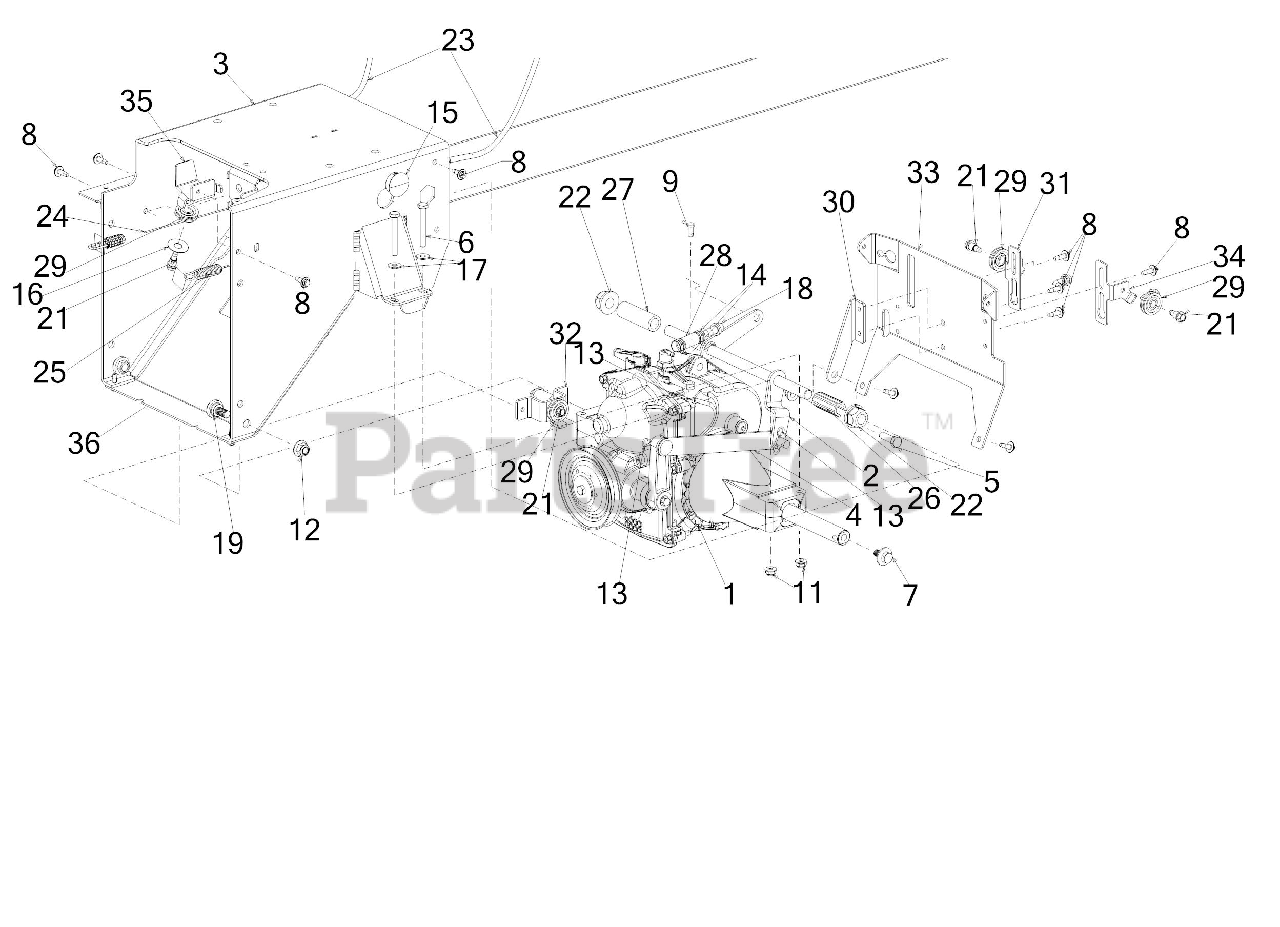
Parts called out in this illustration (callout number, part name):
1	HYDRO TRANSMISSION ASSEMBLY
2	CONTROL SHAFT ASSEMBLY
3	DRIVE FRAME
4	SHIFT LINKAGE
5	SCREW 5/16-18 x 1.0 GR5
6	SCREW 1/4-20 x 2 GR5
7	SCREW 5/16-24 x .750 GR5
8	SCREW M6-1 x .625
9	CLEVIS PIN .25 x .50
11	FLANGE LOCK NUT
13	BOW TIE COTTER PIN 1/4-5/16
14	HOSE CLAMP
15	PLASTIC PLUG
16	FLAT WASHER
17	FLAT WASHER .271:.630:.065
19	SHOULDER SCREW .625X.165X3/8-16
21	SHOULDER SCREW
22	FLANGE BEARING
23	STEERING CABLE
24	WHEEL DRIVE CABLE 48.31"
25	AUGER DRIVE CABLE 48.23"
26	SPACER-.491 ID x 1.67 LG
27	SLEEVE SPACER .525 X .78 X 2.36
28	FUEL HOSE LOW PERMEATION
29	CABLE GUIDE ROLLER
30	TRANSMISSION MOUNTING BRACKET
31	CABLE IDLER BRACKET (RH)
32	DRIVE CABLE GUIDE BRACKET
33	FRAME PLATE (REAR)
34	CABLE IDLER BRACKET (LH)
35	AUGER CABLE GUIDE BRACKET
36	LOWER DRIVE FRAME COVER
